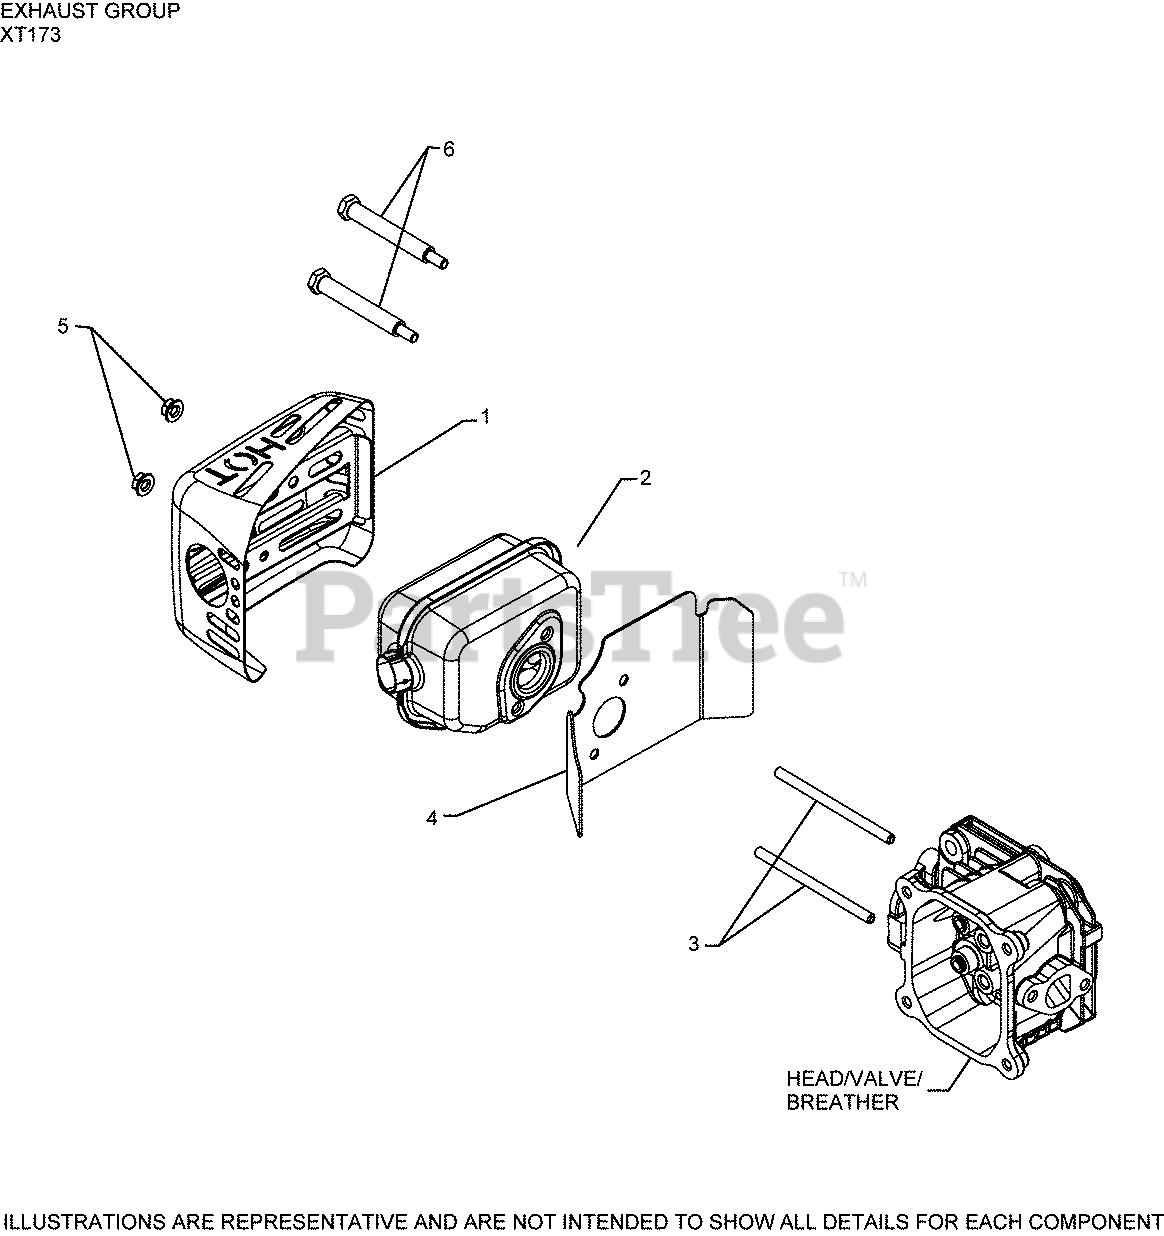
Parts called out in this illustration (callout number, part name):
1	GUARD, MUFFLER
2	KIT, MUFFLER
3	STUD (M6)
4	GASKET, MUFFLER USE 14 041 55-S
5	NUT, HEX FLANGE LOCK (M6)
